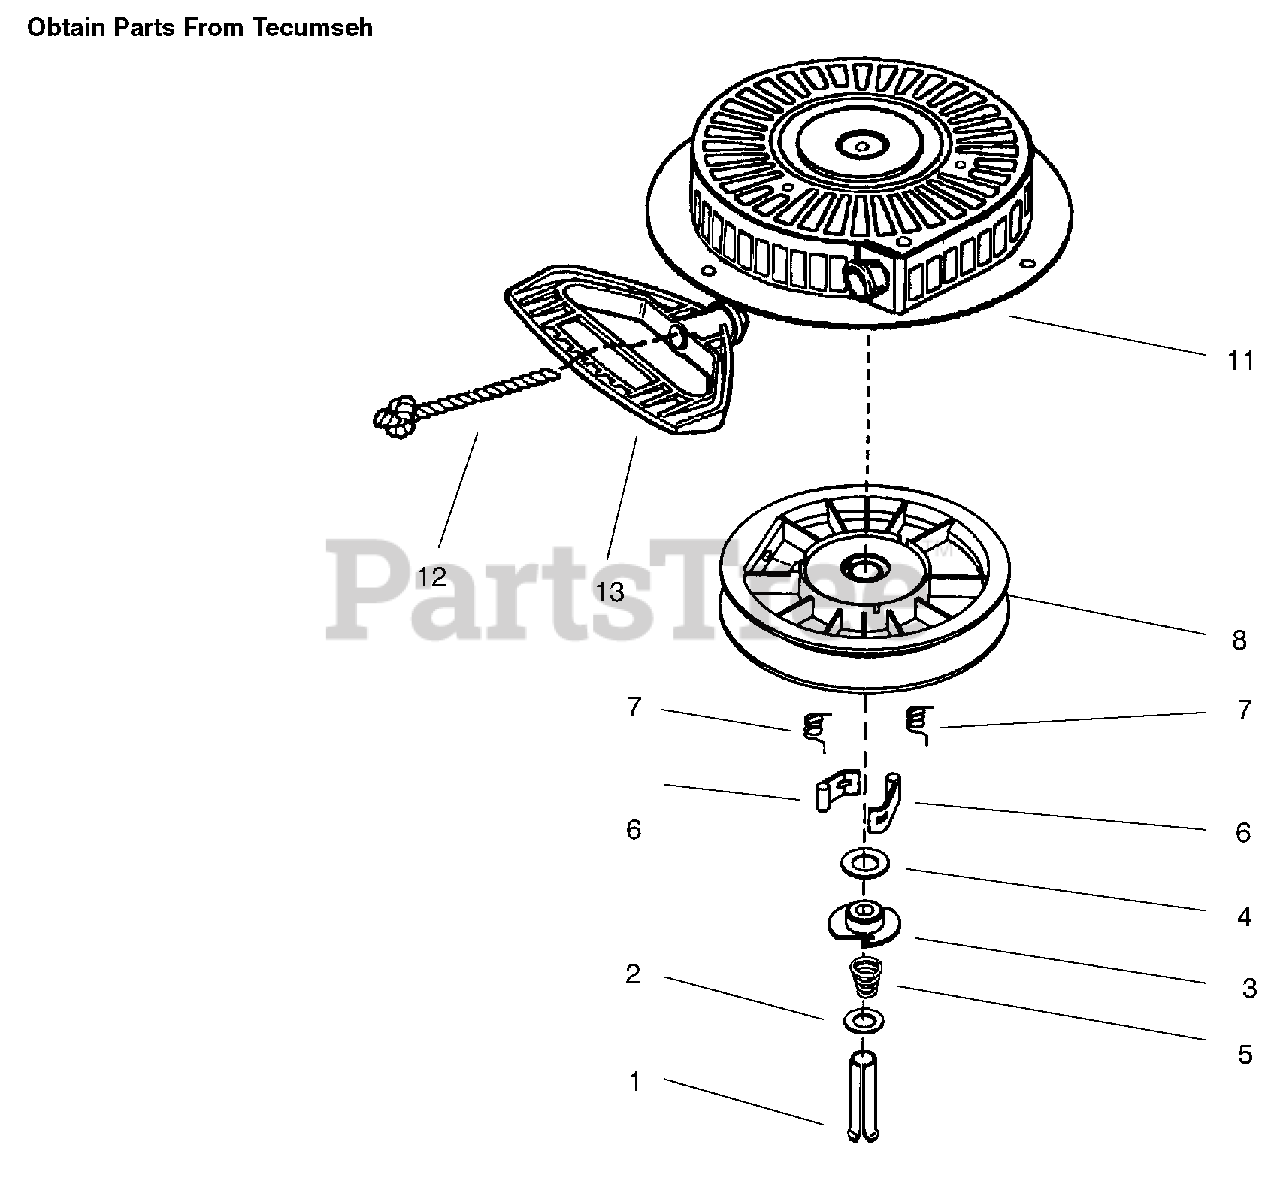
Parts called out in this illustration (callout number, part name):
1	Pin-Spring (Incl. Ref. #4)
2	Washer
3	Retainer
4	Washer
5	Spring-Brake
6	Dog-Starter
7	Spring-Dog
8	Pulley and Rewind Spring ASM
11	Starter Housing ASM
12	98 Starter Rope (cut to length)
13	Handle-Starter, Mitten Grip
